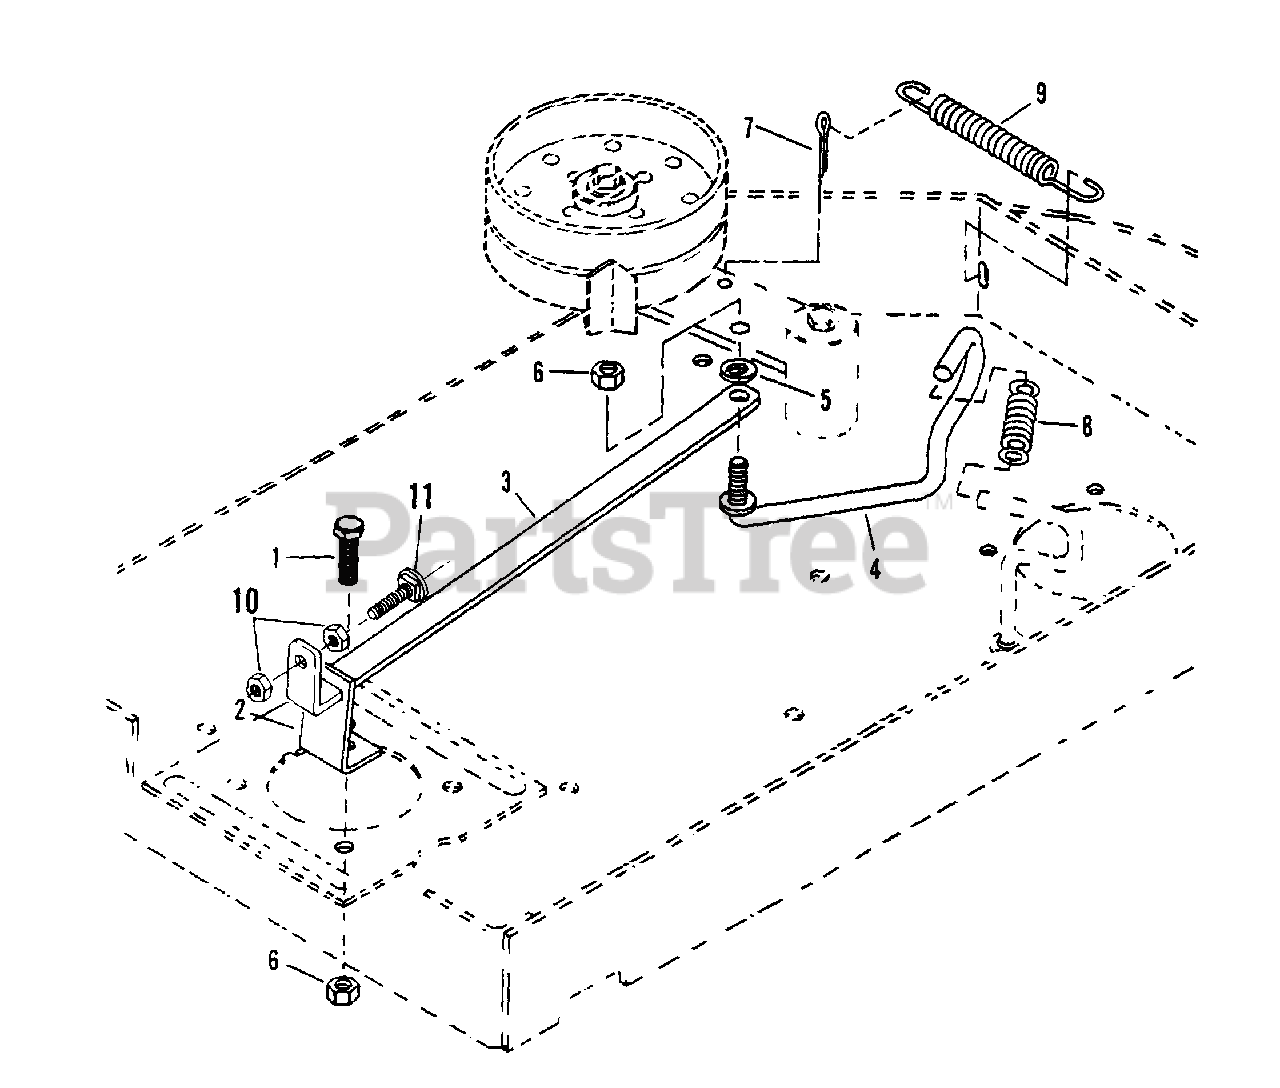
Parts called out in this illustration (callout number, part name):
1	SCREW, 3/8-16 x 1-1/2" Hex Cap
2	BRACKET, Brake
3	ARM, Brake
4	GUIDE, Brake Belt
5	WASHER, 3/8" Spring
6	NUT, 3/8-16 Hex Nyloc
7	PIN, Cotter
8	SPRING, Traction
9	SPRING, Idler Return
10	NUT, 5/16C Hex Jam
11	BOLT, 5/16C x 1-1/4" Grade 2 Carriage
